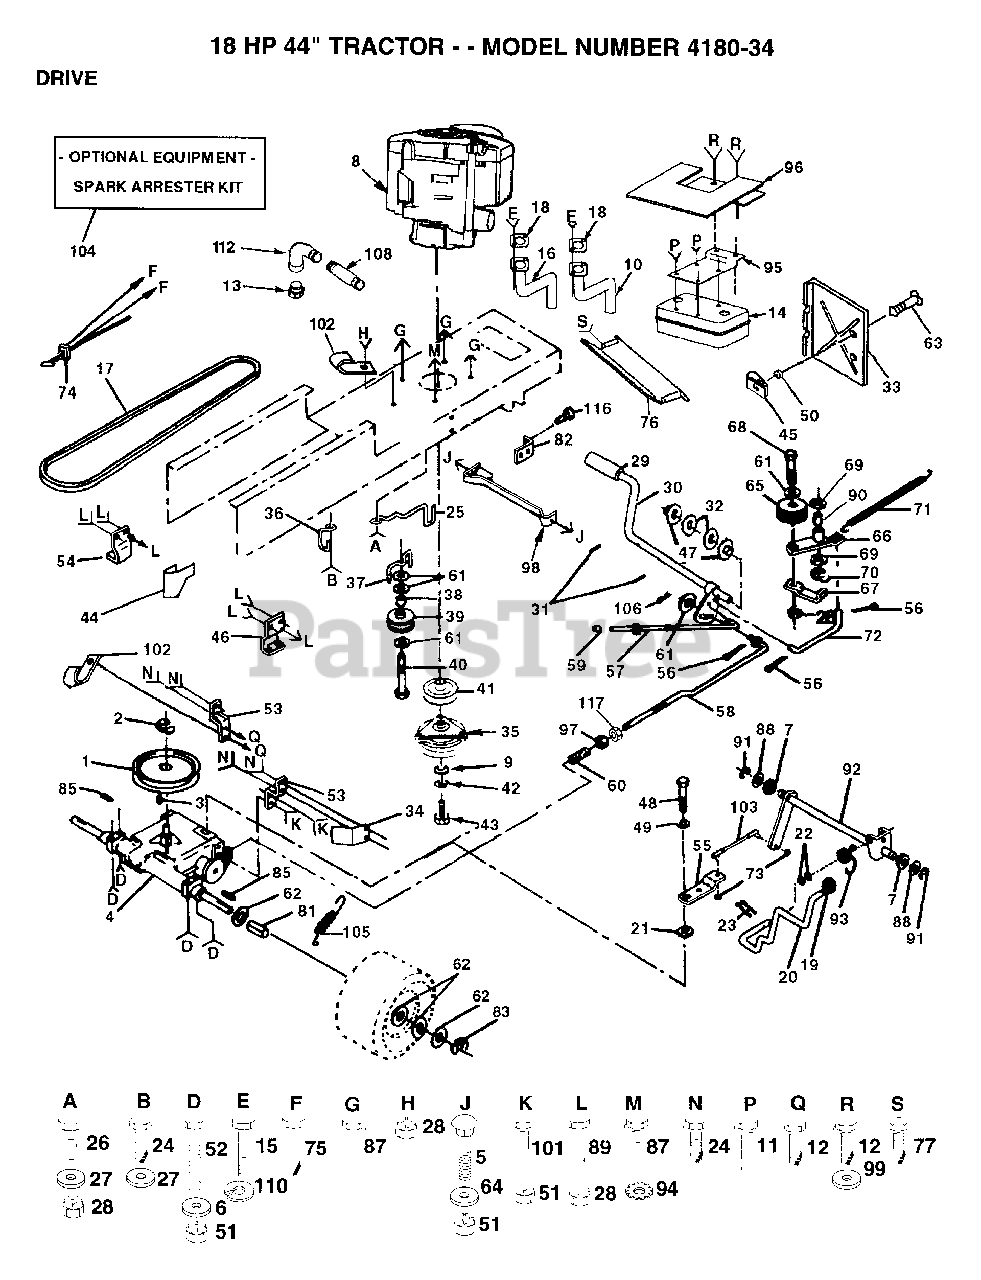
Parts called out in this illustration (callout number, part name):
1	PULLEY TRANSAXLE
4	TRANSAX. PRLES.
5	BOLT
6	WASHER
7	BUSHING
9	WASHER
11	SCREW ST
12	SCREW
16	EXHAUST ASM LH
17	BELT.GRDRV.94.75
19	KNOB T (1/2-HOLE)
21	WASH-SHFT PLT LT
22	WASHER
23	PIN COTTER 1/8
24	SCREW
25	KEEPER.BELT.ENG.L
26	BOLT
27	WASHER
29	PEDAL COVER T
32	WASHER LT
33	HEAT SHIELD
34	"KEEPER,BELT RH"
37	BELT KEEPER LT
38	SPACER T
39	PULLEY.IDLER.FLAT
40	BOLT
41	PULLEY ENGINE
42	LOCKWASHER
44	KEEPER BELT LH
45	RECEPTACLE LT
46	BRKT TRANS RH
47	NYLON BEARING
49	WASHER PM
50	RETAINER LT
52	BOLT
53	STRAP TORQUE
54	BRKT TRANS LH
55	"ARM,SHIFT"
56	COTTER PIN
57	BRAKE PARK ROD
58	ROD BRAKE
59	PLUNGER CAP T
60	"SPRING,ROD BRAKE"
61	WASHER
62	WASHER
63	STUD.1/4.TURN
64	WASHER T
66	ARM IDLER
67	RETAIN BELT
69	WASHER LT
70	KLIP RING
71	"SPRING, RETURN LT"
72	"LINK, CLUTCH T"
73	NUT 1/4-28
75	SCREW LT
76	HEAT SHIELD
77	SCREW
81	SPACER HYT
82	BRACKET LT
83	E RING HYT
85	SQ KEY STD
87	SCREW LT
88	WASHER D
90	"LY, BEARING"
91	KLIP RING
92	"SHAFT,SHIFTER"
93	"SPRING,TORSION"
94	LOCKWASHER
95	BRACKET MUFFLER
97	NUT
98	BRACKET.ASM.MTG
99	WASHER
101	BOLT
102	CLIP T
103	"ROD,TIE "
106	RETAINER M
108	PIPE NIPPLE LT
110	LOCKWASHER
112	ELBOW
116	SCREW
117	NUT
